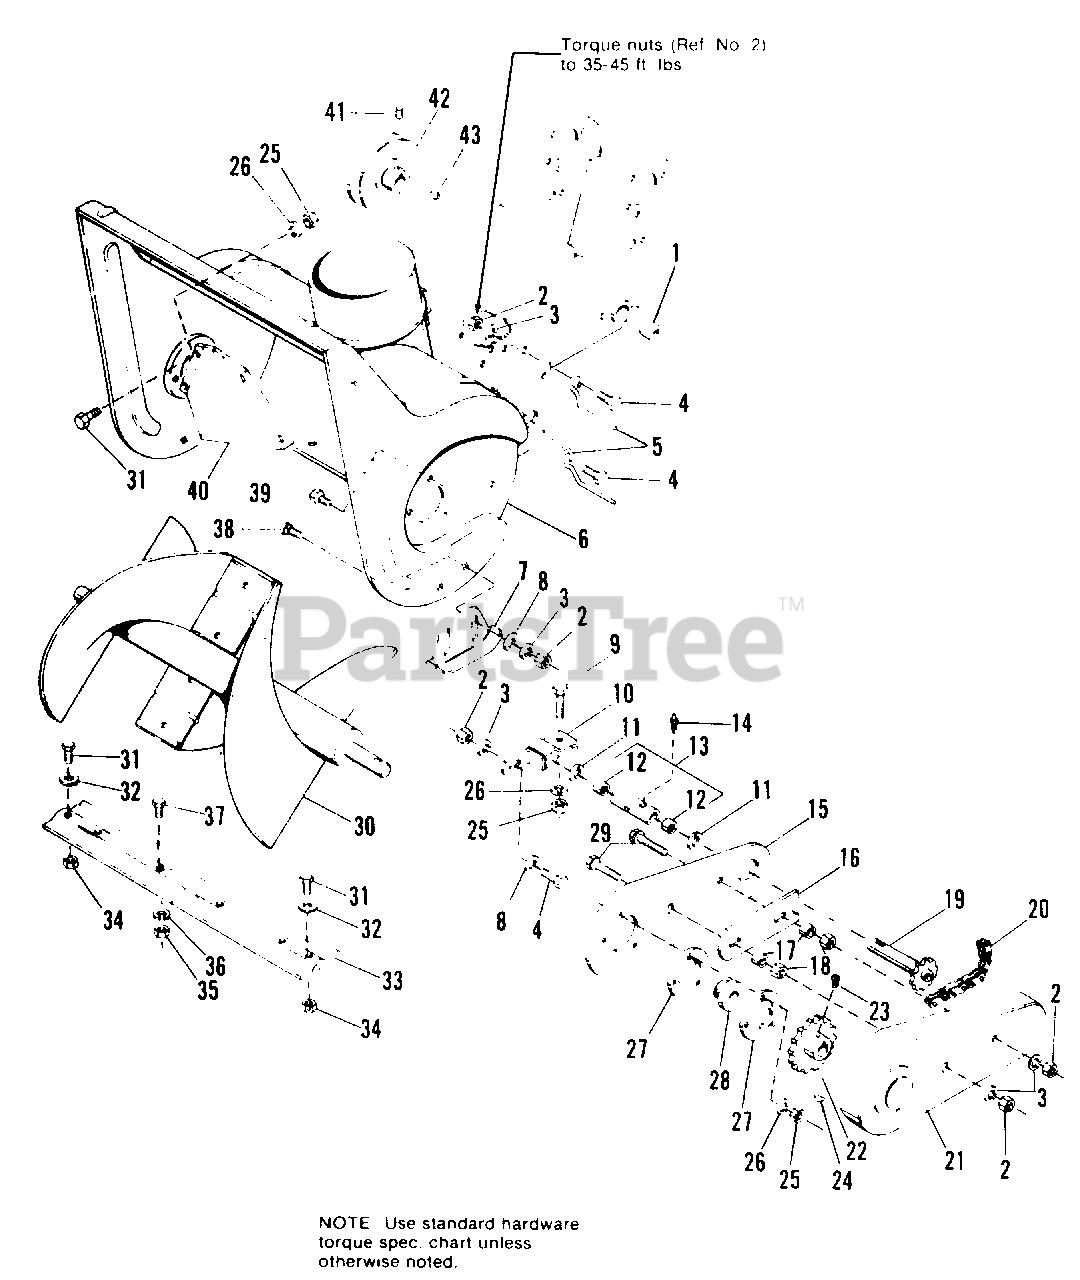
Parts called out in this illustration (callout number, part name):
2	NUT, Hex, Full, 3/8-16
3	LOCKWASHER, 3/8
4	CAPSCREW, Hex 3/8-16 x 1
5	STOP, Belt
6	BODY ASSY., Frame
8	WASHER, Plain, 3/8
9	CAPSCREW, Hex, 5/16-18 x 1-3/4
10	CLAMP, Housing
13	HOUSING ASSY., Bearing
14	FITTING, Grease
15	PLATE, Side
18	NUT, Flange, Whizlock, 3/8-16
19	SHAFT ASSY.
21	GUARD, Chain
23	SETSCREW, 5/16-18 x 1/2
24	KEY, Hi-Pro
25	NUT, Hex, Full, 5/16-18
26	LOCKWASHER, 5/16
27	FLANGE, Bearing
28	BEARING, Cartridge
29	SCREW, Flange, Whiz, 3/8-16 x 2-1/4
30	ROTOR ASSY.
31	CAPSCREW, Hex, 5/16-18 x 5/8
32	WASHER, Plain, 1/4
33	SCRAPER, Body
34	LOCKNUT, Hex, 5/16-18
35	NUT, Hex, Full, 1/4-20
36	LOCKWASHER, 1/4
37	CAPSCREW, Hex, 1/4-20 x 5/8
38	BOLT, Carriage, 3/8-16 x 3/4
39	CAPSCREW, Hex, 5/16-18 x 3/4
41	SETSCREW, 5/16-18 x 5/16
43	KEY, Woodruff, #9
